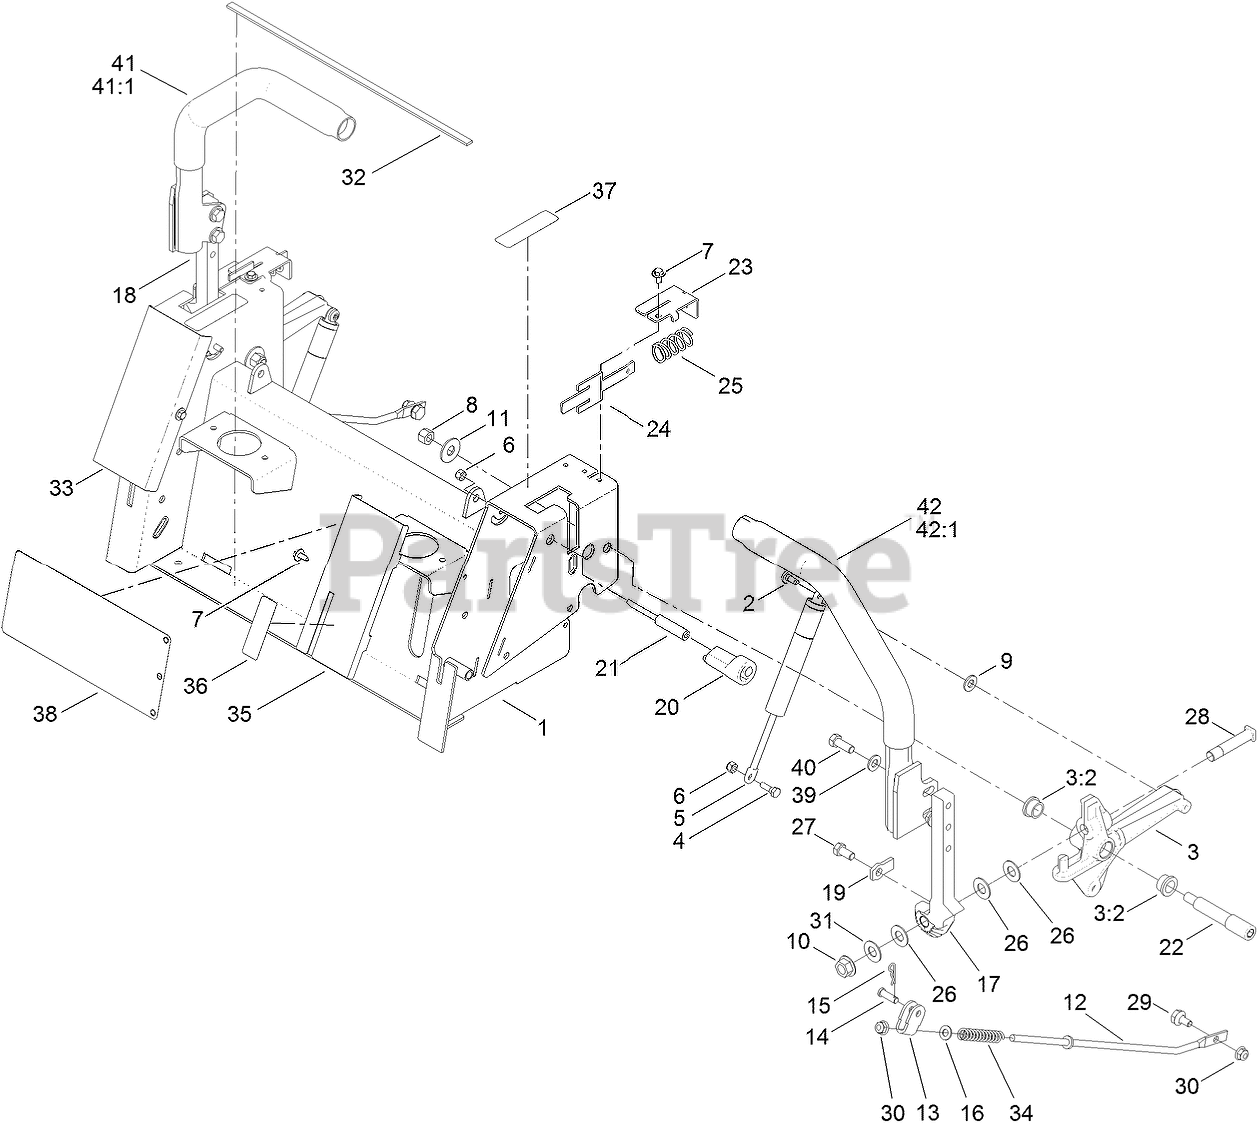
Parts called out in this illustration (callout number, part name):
1	BOX-CONTROL
2	SCREW-SHOULDER
3	ACTIVATOR ARM ASM
3:2	BUSHING
4	BOLT-SHOULDER
5	DAMPER-CONTROL, MOTION
6	NUT-LOCK, NI
7	SCREW-HHFTF
8	NUT-LOCK, NI
9	WASHER
10	NUT-HF
11	WASHER-FLAT
12	ROD-CONTROL
13	BRACKET-CONTROL
14	PIN-CLEVIS
15	PIN-COTTER
16	WASHER-PLAIN
17	ARM-ACTUATOR, LH
18	ARM-ACTUATOR, RH
19	TAB-STOP
20	ECCENTRIC
21	SCREW-ECCENTRIC
22	BOLT-SHOULDER
23	BRACKET-RETURN
24	PLATE-RETURN
25	SPRING-COMPRESSION
26	WASHER-PIVOT
27	SCREW-HH
28	BOLT-SHOULDER
29	BOLT-SHOULDER
30	NUT-HF, NI
31	WASHER-TEFLON
32	STRIP-VIBRATION, ANTI
33	COVER-CONTROL, RH
34	SPRING-RETURN, NEUTRAL
35	COVER-CONTROL, LH
36	DECAL-BRAKE, PARKING
37	DECAL-CONTROL, MOTION
39	WASHER-FLAT
40	SCREW-HH
41	RH LEVER/GRIP ASM
41:1	Grip-Control, Motion
42	LH LEVER/GRIP ASM
42:1	Grip-Control, Motion
